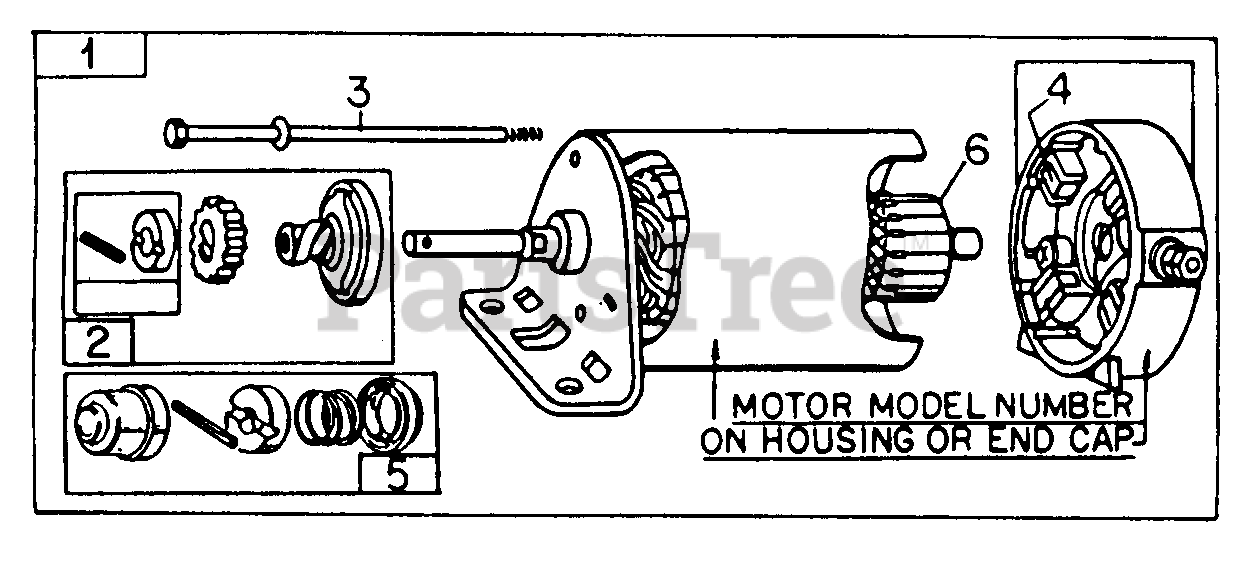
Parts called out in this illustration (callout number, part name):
1	Motor Assy, Starter
2	Drive Assy
3	Bolt, Thru
5	Kit, Pinion Spring
6	Armature Assy
